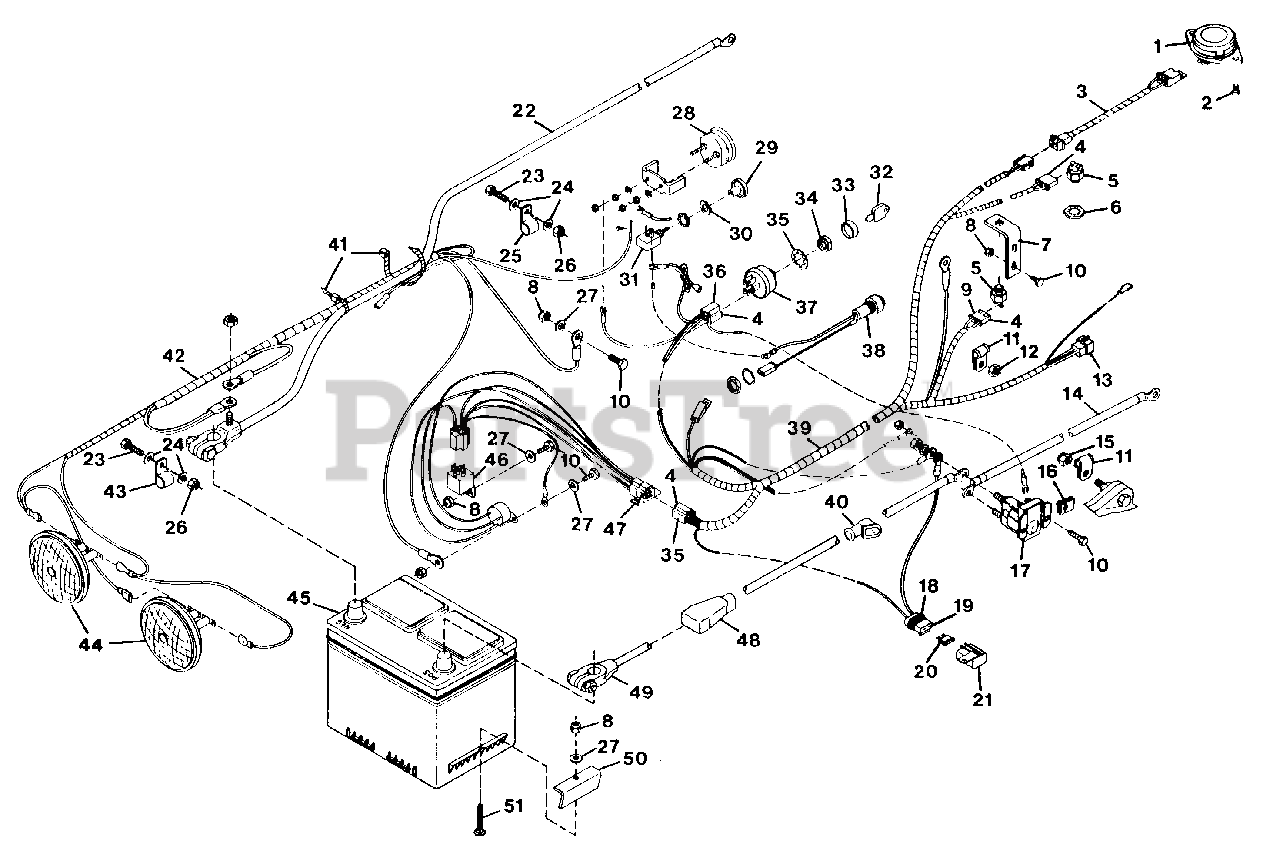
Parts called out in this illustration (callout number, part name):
1	SWITCH, SEAT
2	SCREW, MACHINE 1/4-20
3	HARNESS, WIRING SEAT SWITCH
4	TERMINAL
5	SWITCH, INTERLOCK
6	NUT, STAMPED 9/16-18
7	BRACKET, SWITCH
8	NUT, LOCK 1/4-20
9	CONNECTOR, 2-WIRE SWITCH
10	BOLT, HEX 1/4-20X.75
11	CLAMP
12	NUT, LOCK 3/8-16
13	CONNECTOR
14	CABLE, STARTER
15	NUT, LOCK 3/8-16
16	NUT, SPEED 1/4-20
17	SWITCH, MAGNETIC
18	CONNECTOR
19	TERMINAL, 14-16 GAUGE
20	FUSE, 25 AMP
21	COVER
22	CABLE, NEGATIVE BATTERY
23	BOLT, HEX 5/16-18X1.00
24	WASHER, FLAT .344X.688X.065
25	CLAMP, NYLON
26	NUT, LOCK 5/16-18
27	WASHER, FLAT .281X.625X.065
28	GAUGE, AMMETER
29	KNOB, LIGHT SWITCH
30	NUT, SPECIAL LIGHT SWITCH
31	SWITCH, LIGHT
32	KEY, IGNITION SWITCH
33	BOOT, 9/16 SWITCH
34	NUT, JAM 9/16-24
35	WASHER, LOCK 9/16 INT. TOOTH
36	CONNECTOR
37	SWITCH, IGNITION
38	LIGHT, INDICATOR
39	HARNESS, WIRING
40	BOOT, BATTERY CABLE
41	TIE, CABLE
42	HARNESS, WIRING GROUND AND LIGHT
43	CLAMP, NYLON
44	HEADLIGHT
45	BATTERY, 12 VOLT
46	RELAY
47	MODULE, TIME DELAY
48	COVER, BATTERY TERMINAL
49	CABLE, BATTERY TO MAGNETIC SWITCH
50	CLAMP
51	BOLT, 1/4-20X1.75 RD HD SQ NK
